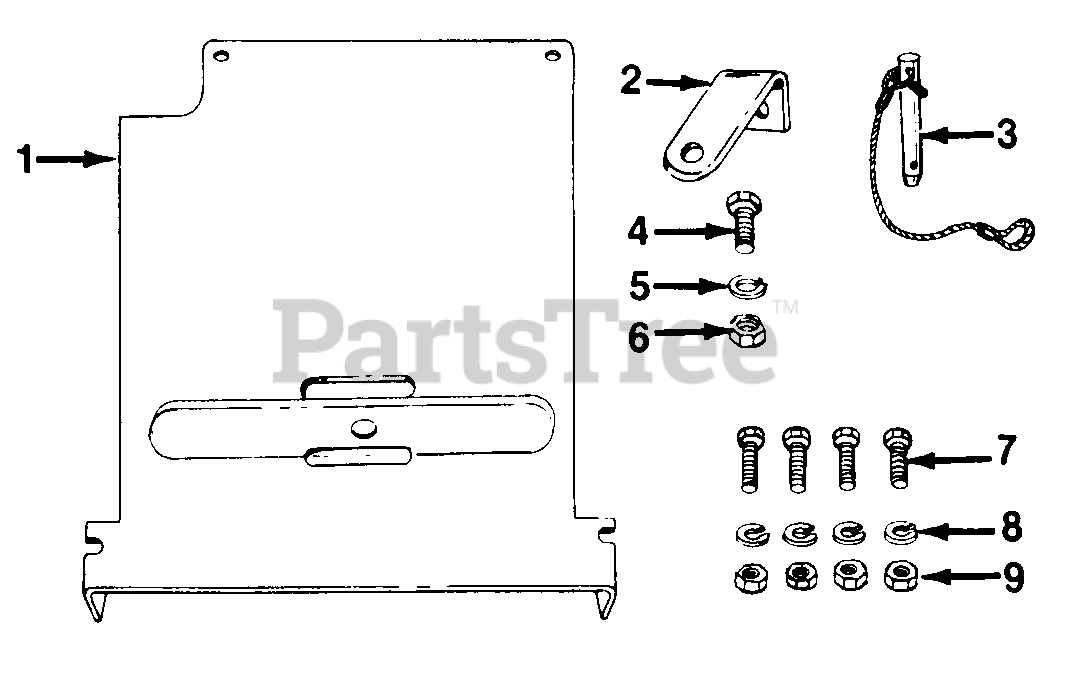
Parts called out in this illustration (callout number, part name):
1	Hitch Plate
2	Hitch Bracket
3	Hitch Pin
4	Hex Bolt 3/8-16 x 1" Lg.
5	L-Wash. 3/8" I.D.
6	Hex Nut 3/8-16 Thd.
7	Hex Bolt 5/16-18 x .75" Lg.*
8	L-Wash. 5/16" I.D.
9	Hex Nut 5/16-18 Thd.
